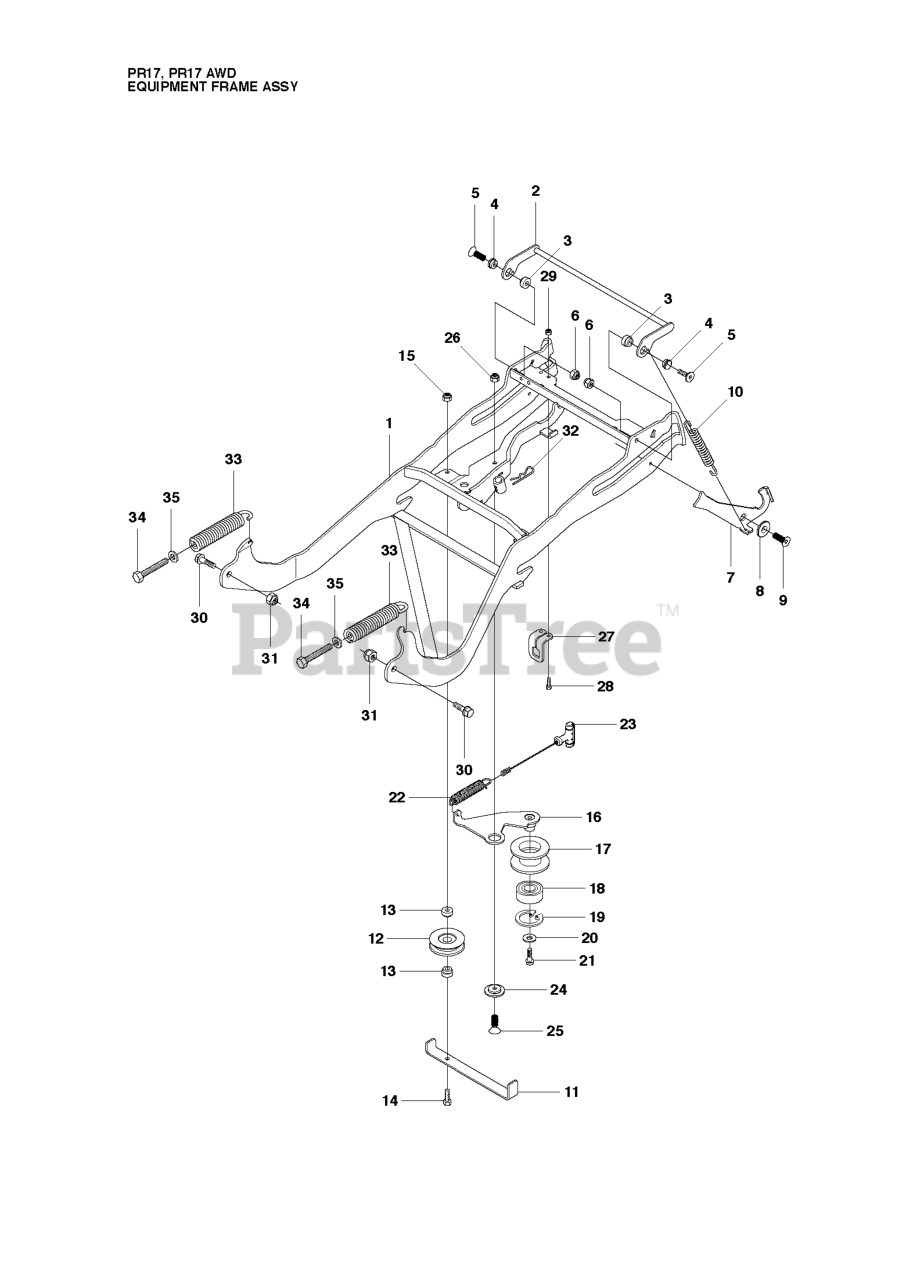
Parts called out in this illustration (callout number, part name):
6	LOCKNUT M8
8	SPACER
9	SCREW IHCSFM
12	PULLEY ASSY
14	SCREW
15	LOCKNUT M8
17	%PULLEY
18	BALL BEARING 6004-2RS1
19	RETAINING RING
24	WASHER
26	LOCKNUT M8
28	BOLT FLANGE - M6X20
29	LOCKNUT M6
35	WASHER
